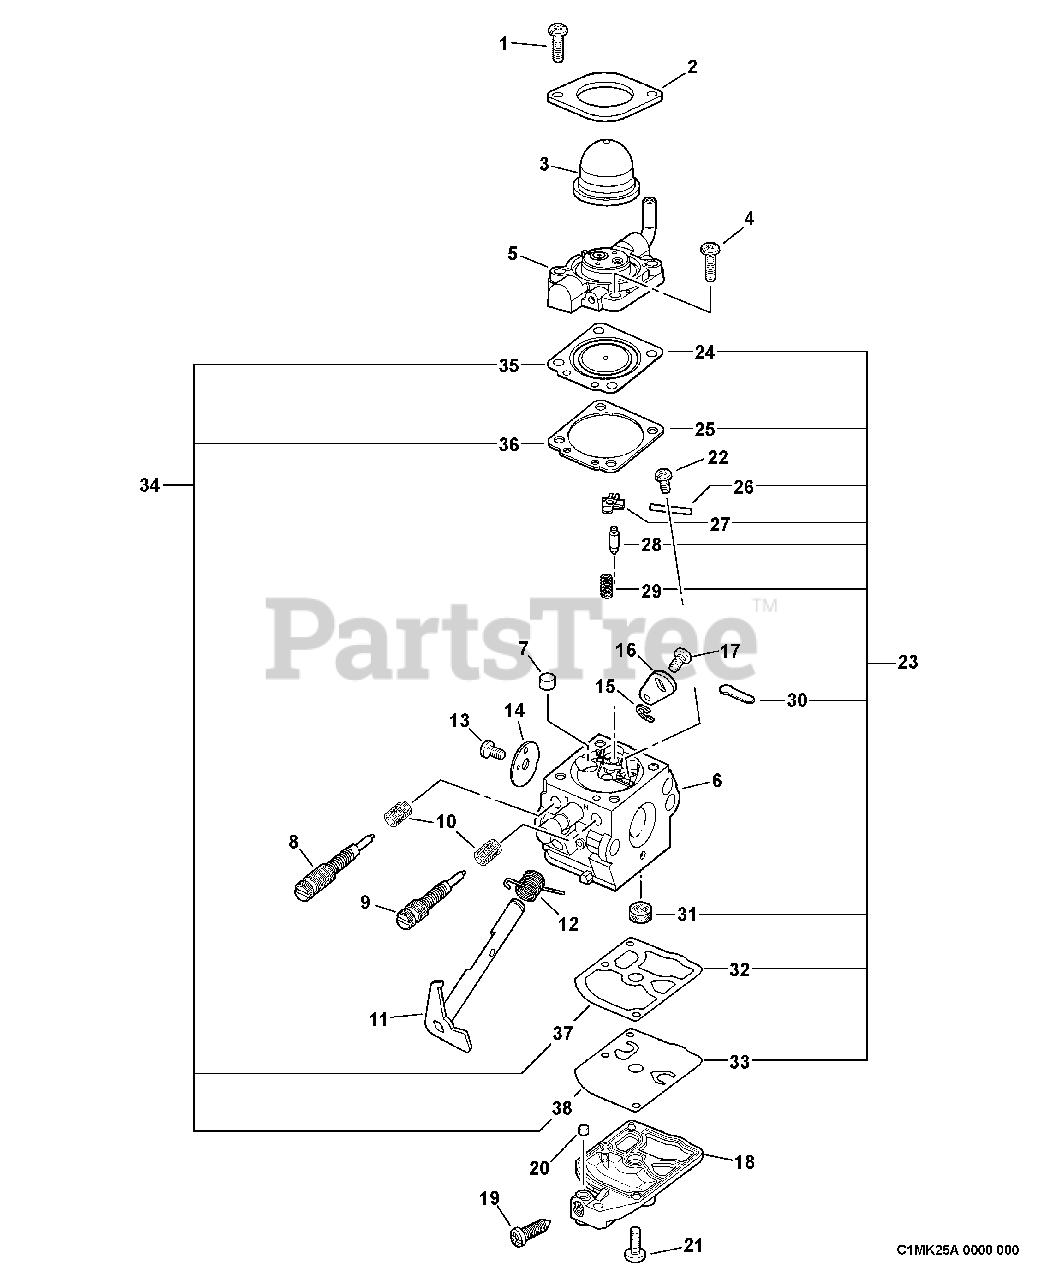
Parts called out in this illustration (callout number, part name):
1	SCREW, RETAINER
2	RETAINER, PURGE BULB
3	BULB, PURGE
4	SCREW, PURGE BASE
5	BASE, PURGE
6	BODY, CARBURETOR
7	NOZZLE, CHECK VALVE
8	NEEDLE - LOW SPEED
9	NEEDLE - HIGH SPEED
11	SHAFT, THROTTLE
12	SPRING, TRIGGER
14	VALVE, THROTTLE
15	RING, RETAINING
16	LEVER, THROTTLE
18	COVER, FUEL PUMP
19	SCREW, IDLE ADJUST
20	PIECE, FRICTION
21	SCREW, PUMP COVER
22	SCREW, METERING LEVER PIN
23	REPAIR KIT
24	DIAPHRAGM, METERING
25	GASKET, DIAPHRAGM
26	PIN, METERING LEVER
27	LEVER, METERING
28	VALVE, INLET NEEDLE
29	SPRING, METERING LEVER
30	PLUG, WELCH
31	STRAINER
32	GASKET, PUMP
33	DIAPHRAGM, PUMP
34	DIAPHRAGM/GASKET KIT
35	DIAPHRAGM, METERING
36	GASKET, DIAPHRAGM
37	GASKET, PUMP
38	DIAPHRAGM, PUMP
